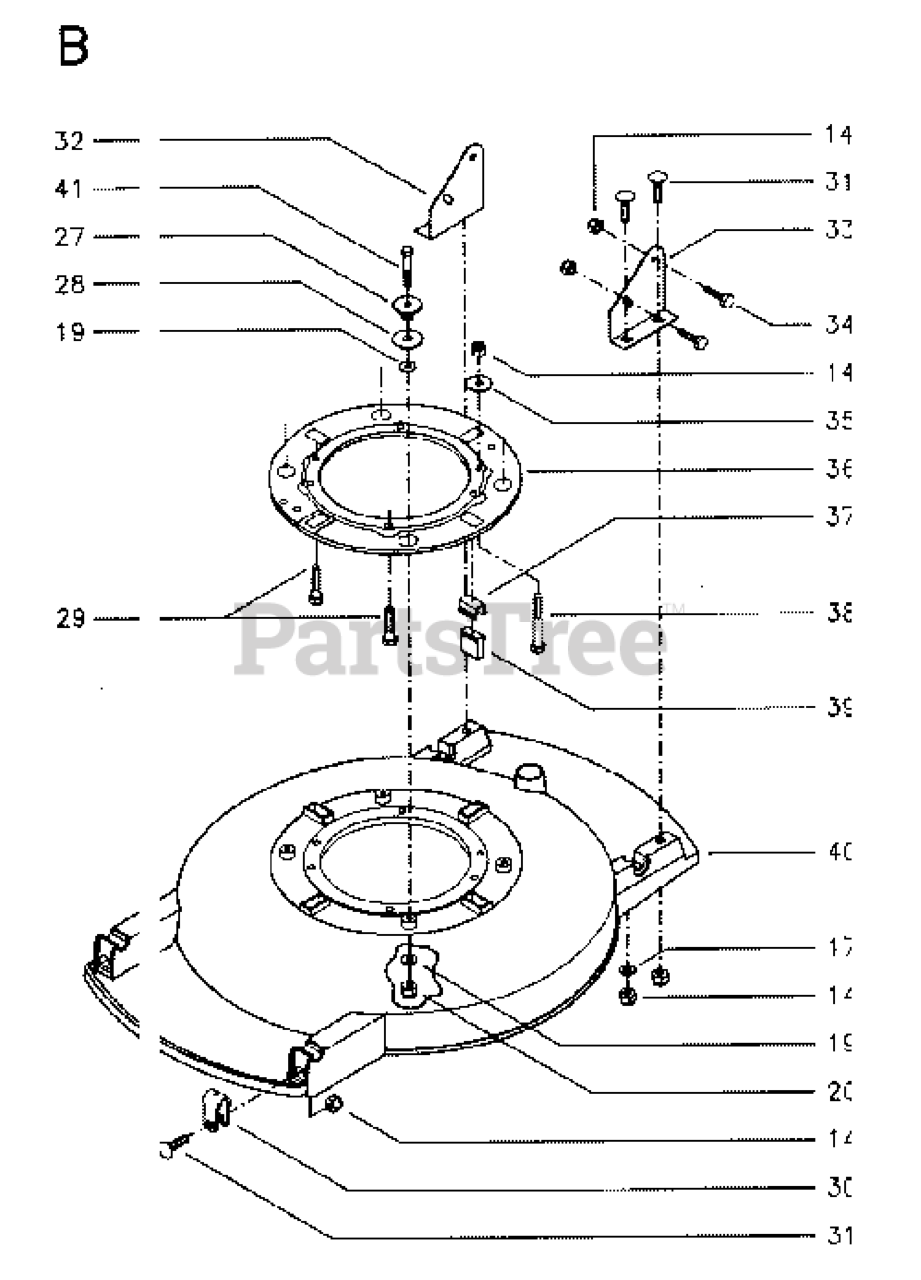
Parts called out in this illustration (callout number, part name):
14	LOCKNUT M8
17	WASHER - 15X7.3X1.6
20	LOCKNUT M6
28	RUBBER PIECE
30	BEARING HOLDER
32	HANDLE BRACKET
33	HANDLE BRACKET
34	BOLT - M8X16
39	DAMPER
